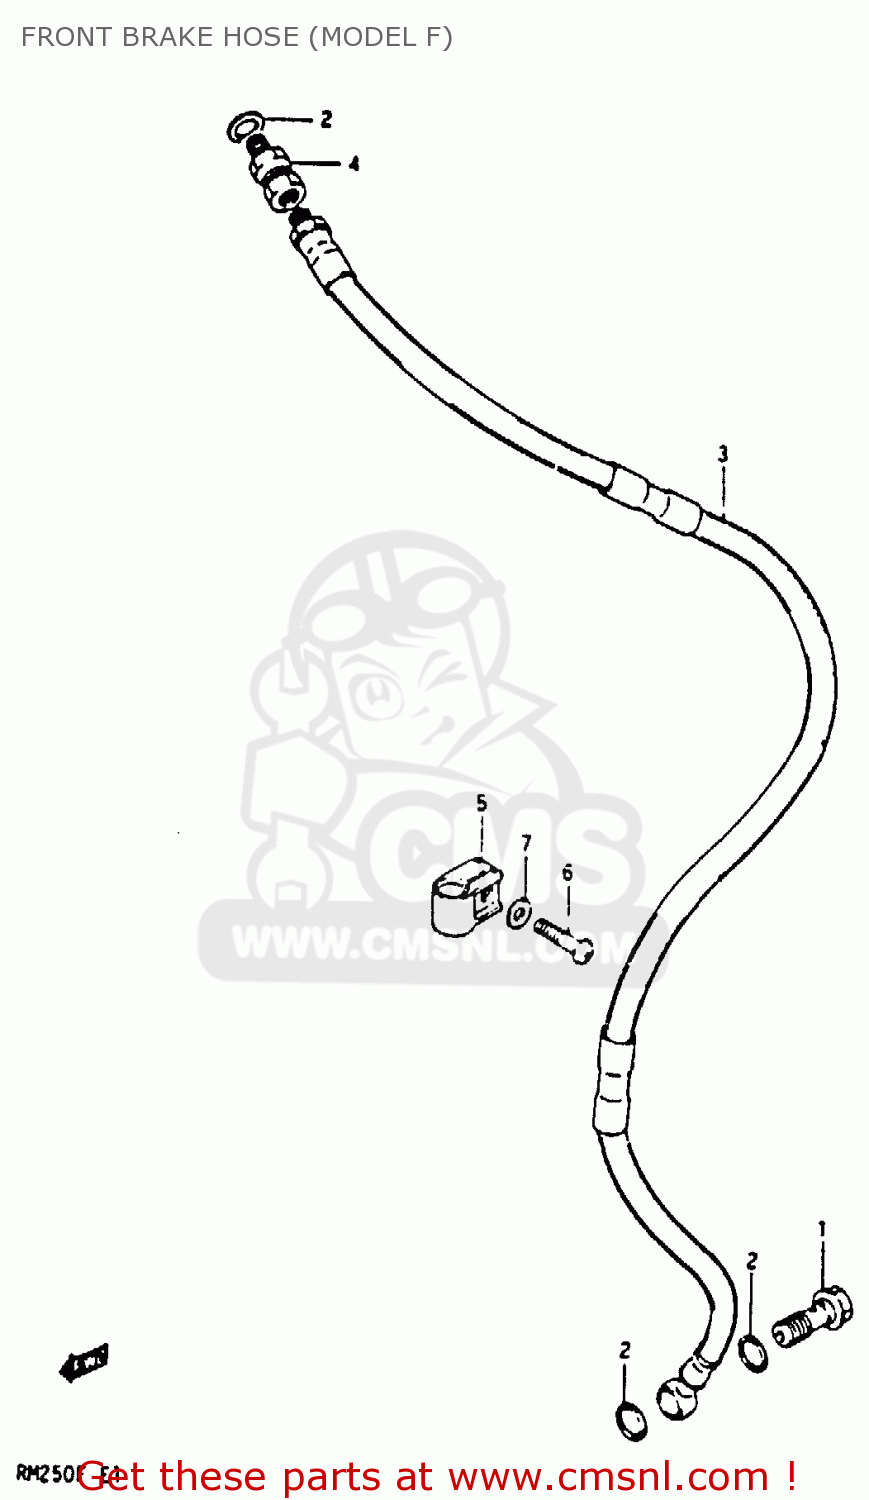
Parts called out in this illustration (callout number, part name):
1	BOLT UNION
2	WASHER(10X15X1.5)
3	HOSE,FRONT BRAKE
4	ADAPTER,BRAKE HOSE
5	CLAMP,FRONT BRAKE HOSE
6	SCREW
7	WASHER
